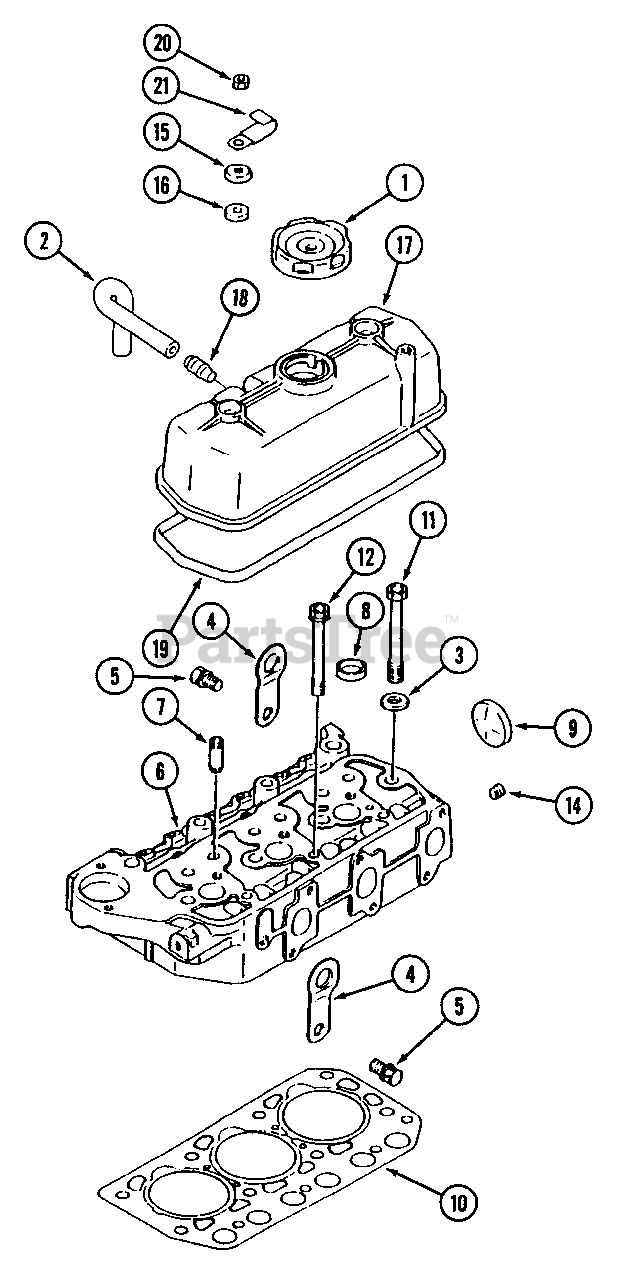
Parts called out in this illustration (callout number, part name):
1	Cap, Oil Filler
2	Pipe, Air Breather
3	Washer, Cylinder Head Belt
4	Hanger, Engine
5	Bolt w/Washer
6	Cylinder, Head Ass'y.
7	Guide, Valve
8	Cap, Sealing
9	Cap, Sealing
10	Gasket, Cylinder Head
11	Bolt, Cylinder Head
12	Bolt, Cylinder Head
14	Plug, Taper
17	Rocker, Cover
18	Pipe
19	Gasket, Rocker, Cover
